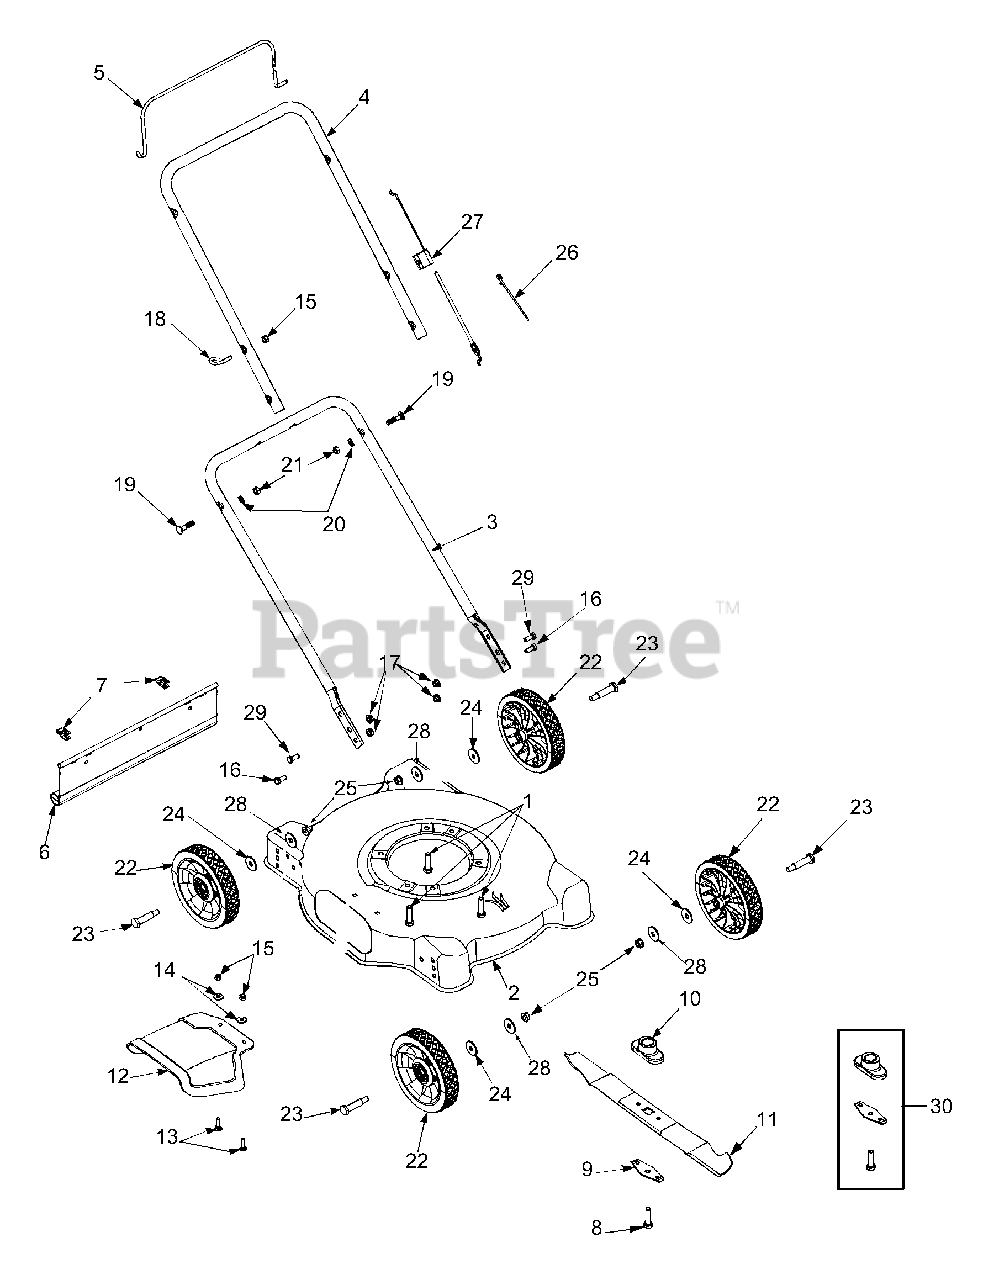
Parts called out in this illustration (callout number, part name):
1	Hex Ind. Washer Screw 3/8-16 x 1.0
6	Rear Flap
7	Hinge Clip
8	Screw 3/8-24 x 1.5" Group 8
9	Blade Bell Support
10	Blade Adapter
11	Cutting Blade
12	Discharge Chute
13	Carriage Screw 1/4-20 x 1.0"
14	Flat Washer
15	Lock Nut 1/4-20
16	Hex Bolt 5/16-18
17	Lock Nut 5/16-18
18	Eye Bolt
19	Carriage Bolt 5/16-18 x 1.5"
20	Lock Washer
21	Nut 5/16-18
22	Wheel
23	Shoulder Screw .498 x 1.635
24	Bell Washer
25	Flange Lock Nut
26	Cable Tie
27	Control Cable (Model 021)
28	Bell Washer
29	Shoulder Screw, 3/8-16x.428
30	Blade Adapter Kit
